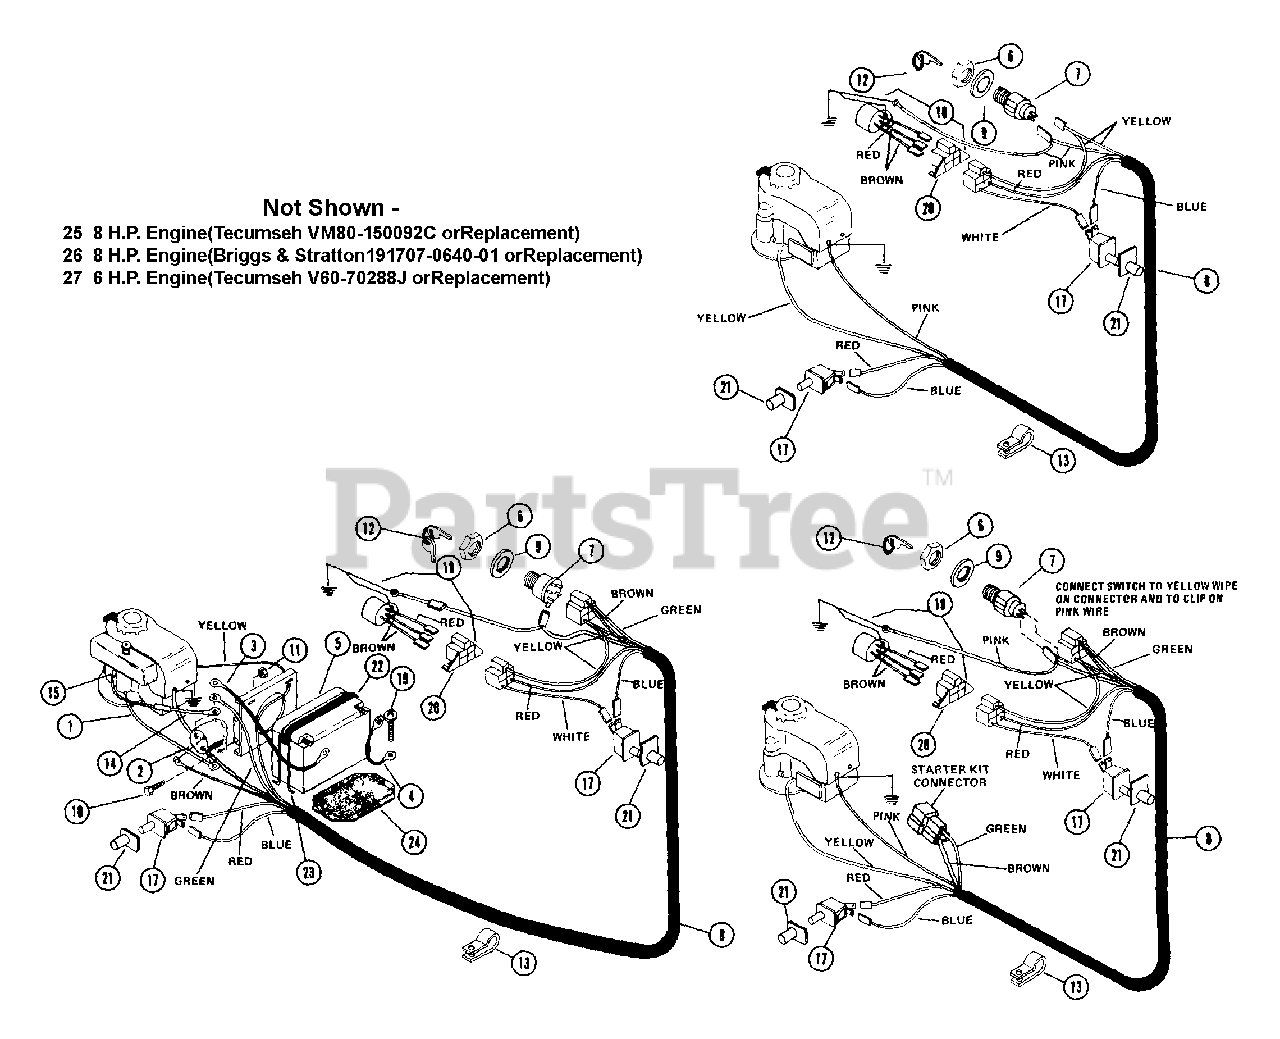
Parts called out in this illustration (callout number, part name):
1	GROUND CABLE .25X13.00X.31
2	SOLENOID,STARTER SWITCH
3	GROUND CABLE
4	GROUND WIRE
5	BATTERY
6	NUT .625-32 ALUM
7	IGNITION SWITCH ASSEMBLY
7	KEY SWITCH
8	WIRING HARNESS
8	WIRING HARNESS-B&S
9	WSHR-LK-INT .625X.045 PL
10	BLT-HEX .25-20X.50 PL GR2
11	NUT-LK-CTR .250-20 PL
12	KEYS
13	CLIP
14	MUFFLER
15	FUSE
18	MODULE T KIT
18	MODULE B KIT
19	SCR-TAP 10-24X.375 CRPH 1A
20	CONNECTOR
21	SCR-TAP 12-24X.50 HWH PL TR
22	BATTERY STRAP
23	HOOK
24	RUBBER PAD
25	8 H.P. Engine(Tecumseh VM80-150092C orReplacement)
26	8 H.P. Engine(Briggs & Stratton191707-0640-01 or Replacement)
27	6 H.P. Engine(Tecumseh V60-70288J) orReplacement)
